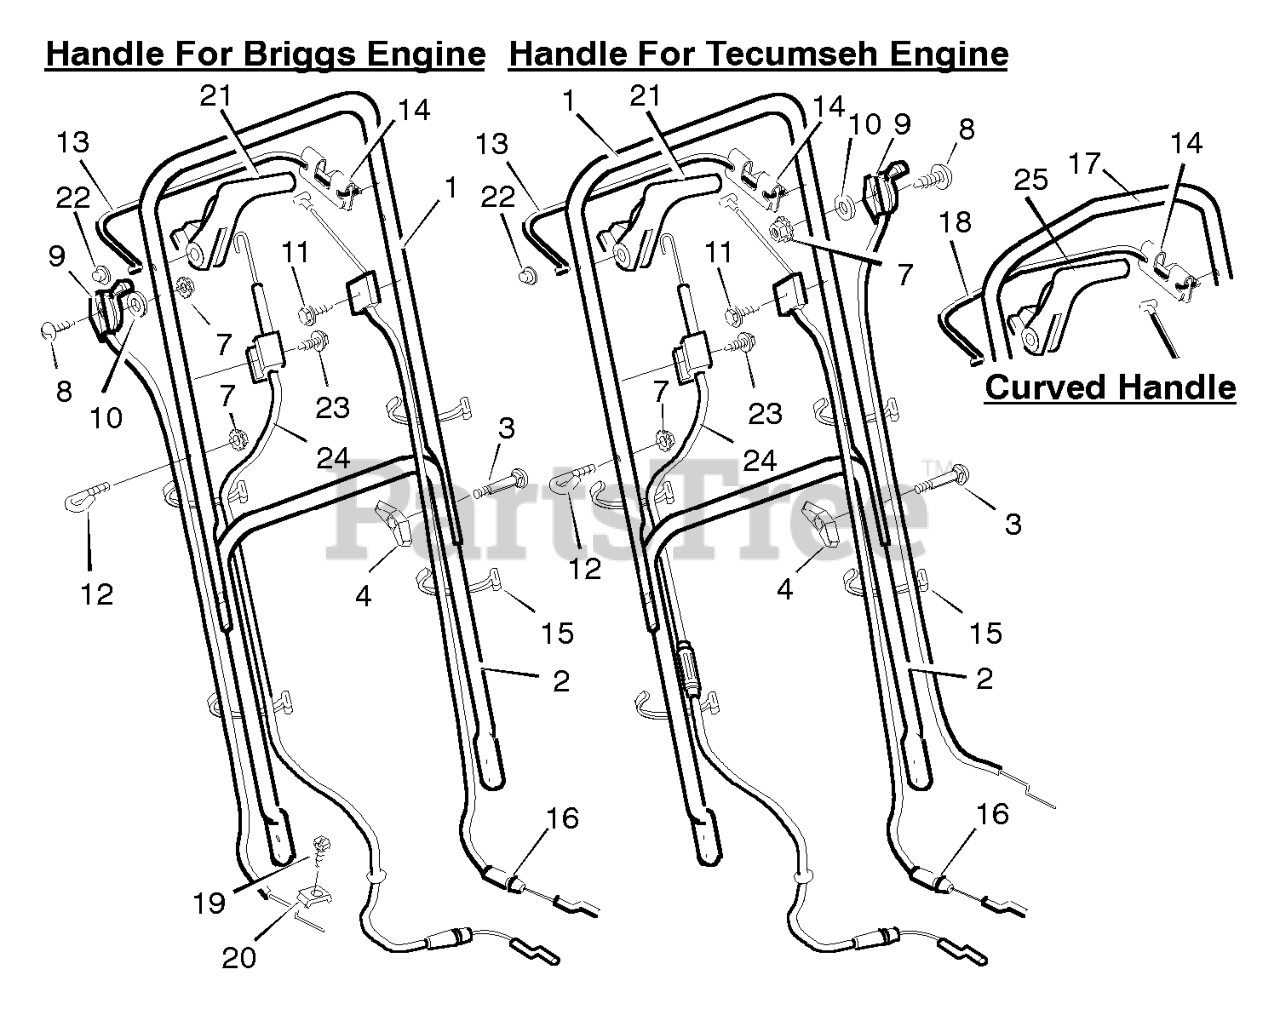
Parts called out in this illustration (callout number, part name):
1	Handle, Upper-Straight (Black)
2	Handle, Lower (Black)
4	Knob, Plastic
7	Locknut
9	Throttle Control
10	Washer
12	GUIDE, ROPE
13	Stop Lever - Straight
14	Bracket, Stop Lever
15	Fastener, Cable
16	Engine Stop Cable *
17	Handle, Upper- Curved (Black)
18	Stop Lever - Curved
19	Screw *
20	Clamp
21	Lever, Drive - Straight
22	Push On Cap
24	Cable, Drive
25	Lever, Drive - Curved
